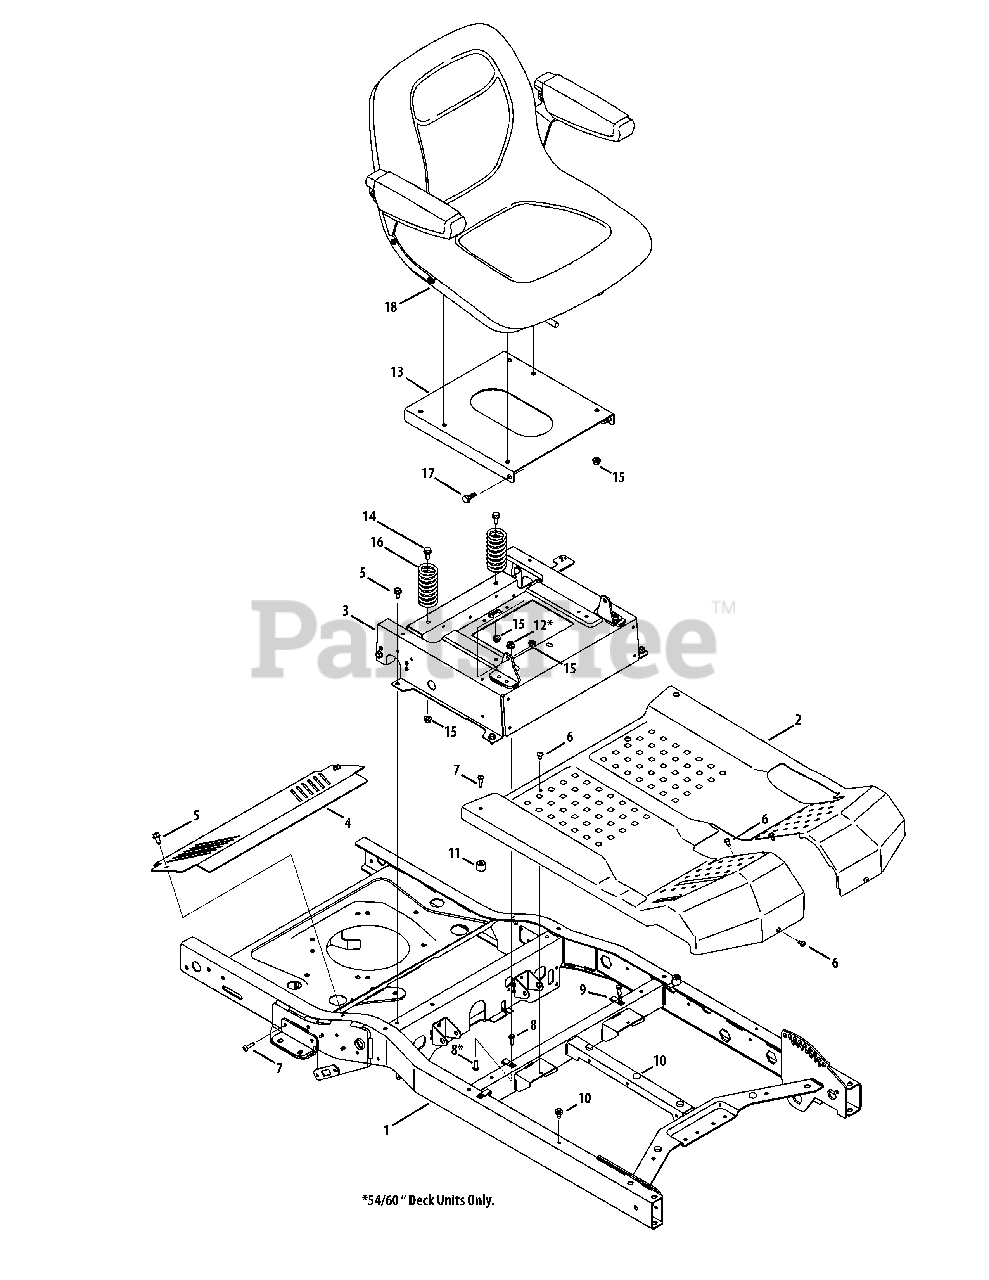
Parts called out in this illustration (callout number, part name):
1	Frame Assembly (46" & 48" Decks)
1	Frame Assembly (54" & 60" Decks)
3	Seat Box Assembly
4	Transmission Cover
5	Hex Washer Screw, 5/16-18 x .750
6	Screw, 1/4-20 x .5
7	Screw, 1/4-20 x 1.0
8	Hex Screw, 1/4-20 x .75
9	Speed Nut, U-Type 1/4-20
10	Rubber Bumper
11	Spacer, .281 x .750 x .680
12	Flange Lock Nut, 1/4-20 (54/60" Deck Units only)
13	Seat Base
14	Hex Washer Screw, 5/16-18
15	Flange Lock Nut, 5/16-18
16	Comp. Spring, 1.71 x 3.735 x .238
17	Shoulder Screw, 5/16-18 x .437 x .268
18	Seat w/ Armrests
